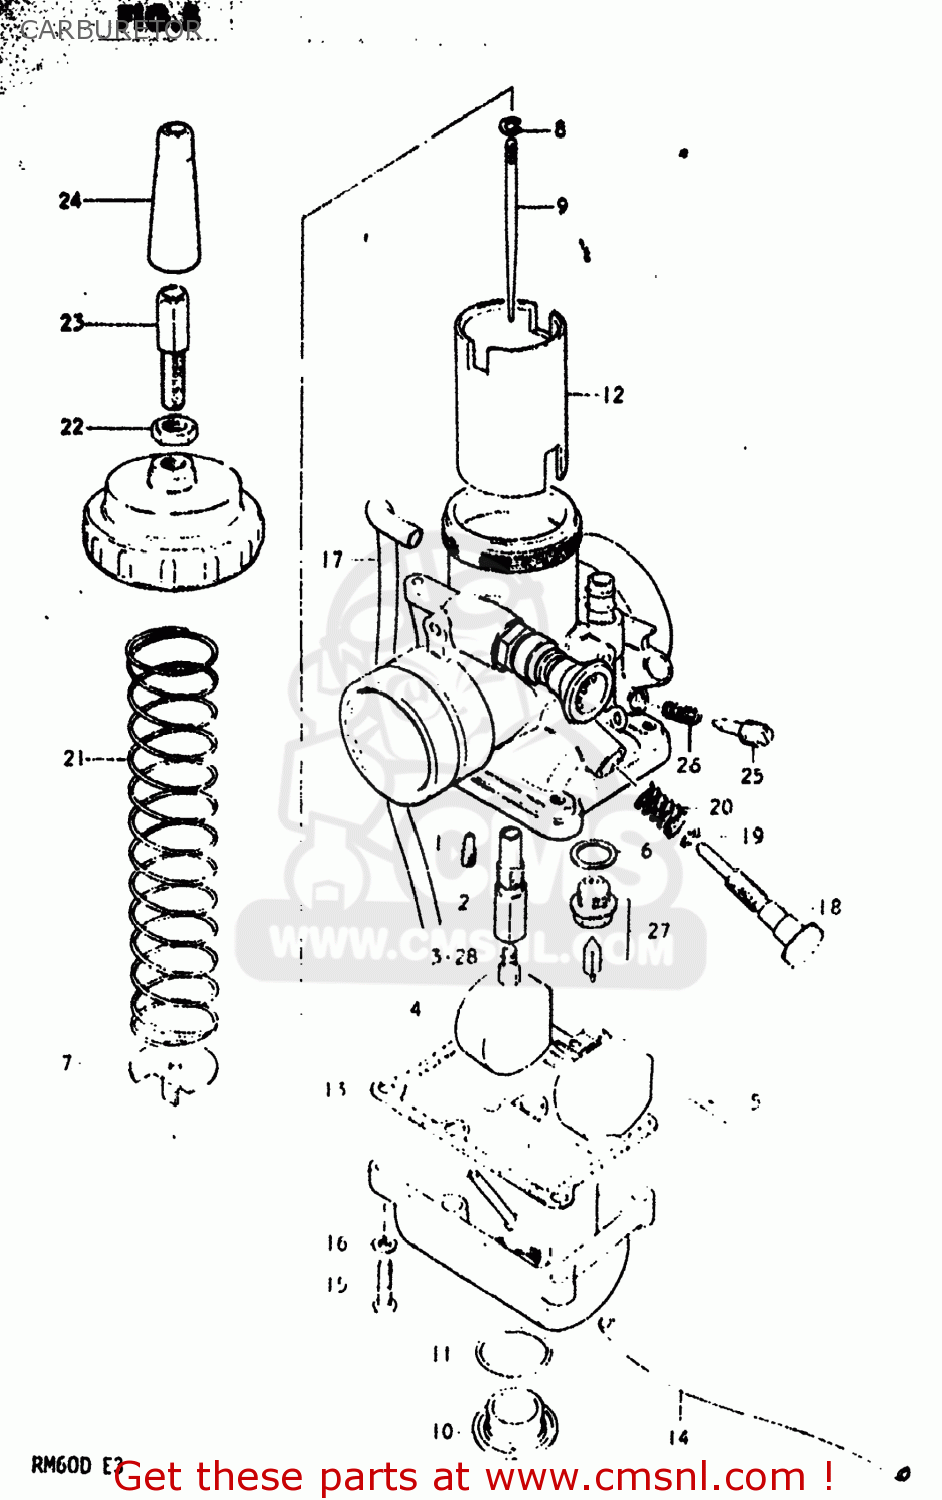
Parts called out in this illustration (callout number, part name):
1	JET,PILOT (17.5)
2	JET,NEEDLE
3	JET
4	FLOAT
5	PIN,FLOAT
6	GASKET,NEEDLE VALVE (NAS)
7	STOPPER,NEEDLE CLIP
8	CLIP
9	NEEDLE JET
10	SCREW,GUIDE
11	O RING(D:1.5,ID:19.5)
12	VALVE,THROTTLE
13	GASKET,FLOAT CHAMBER (NAS)
14	HOSE
15	SCREW
16	LOCK WASHER
17	HOSE
18	ADJUSTER
19	O RING
20	SPRING
21	SPRING,THROTTLE VALVE
22	NUT
23	ADJUSTER,CABLE
24	CAP,CABLE ADJUSTER
25	SCREW,PILOT AIR
26	SPRING
27	VALVE ASSY,NEEDLE
28	JET
